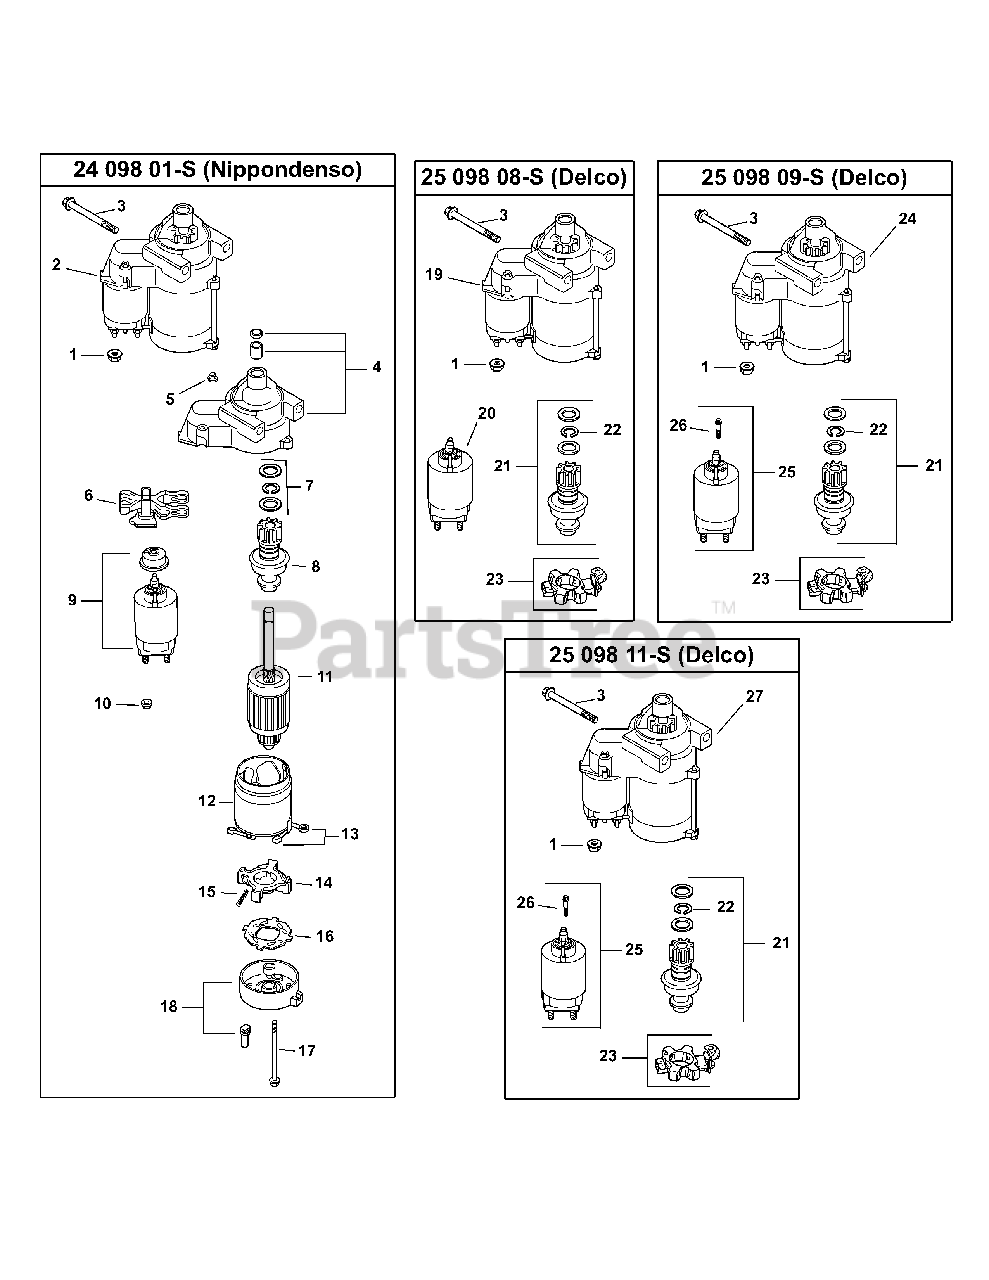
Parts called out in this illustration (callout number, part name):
1	Flange Nut, M8 X 1.25
2	Solenoid Shift Starter Assembly
3	Flange Screw, M8 x 1.25 x 80
4	End Cap Drive
7	Starter Repair Kit
8	Pinion Drive
12	Frame w/ Brushes
13	Brush Holder
14	Brush & Spring Kit
15	Brush Spring
18	End Cap Commutator
19	Solenoid Shift Starter Assembly
21	Starter Pinion Kit (Inc. 22)
22	Retaining Ring
23	Brush Holder Kit
24	Solenoid Shift Starter Assembly
25	Solenoid Kit (Inc. 26)
26	Torx Head Screw
27	Solenoid Shift Starter Assembly
